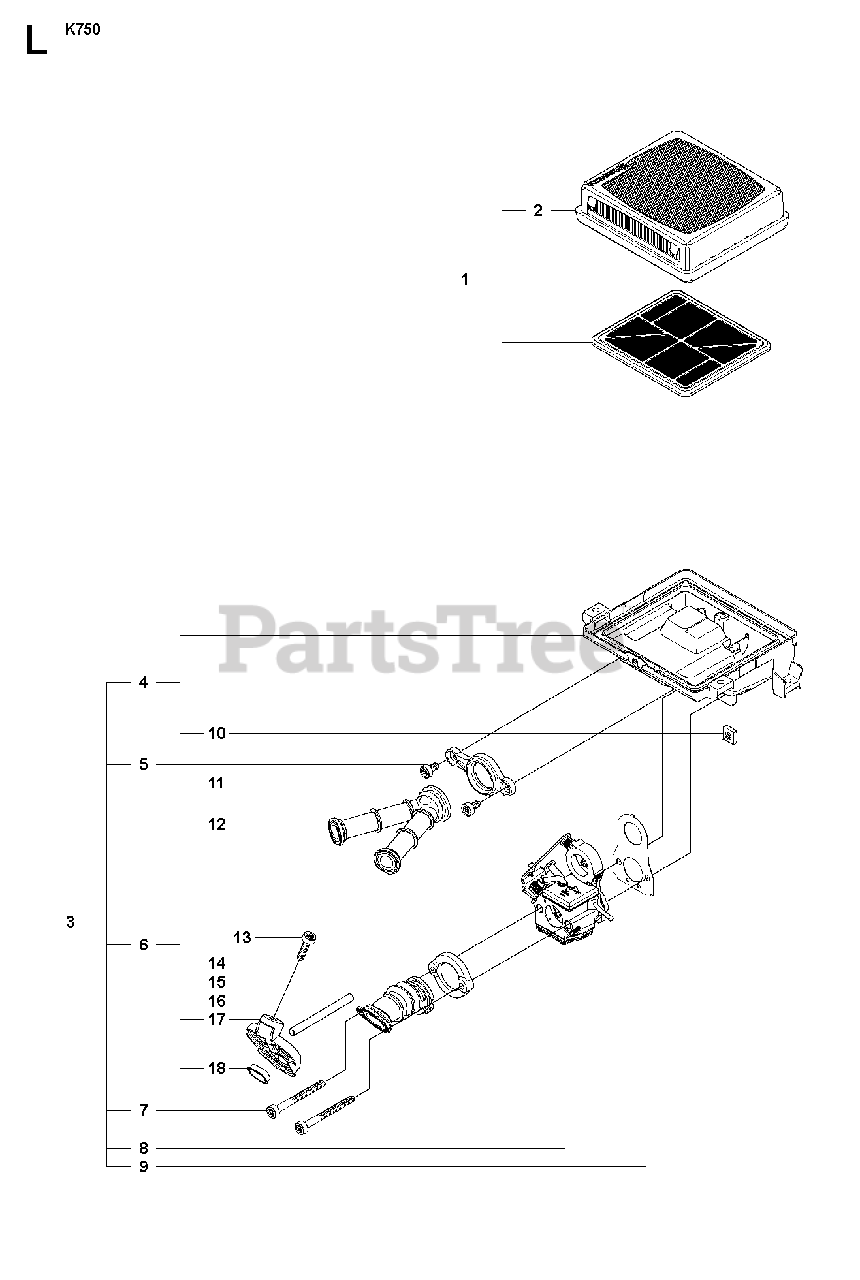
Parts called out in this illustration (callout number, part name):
1	FILTERIncl. 2
2	AIR FILTER
3	CARBURETTOR BRACKETIncl. 4 - 9
4	CARBURETTOR BRACKETIncl. 10
5	SCREW ITXSCM
6	INLET PIPEIncl. 11, 12. 14 - 18
7	SCREW ITXSCM
8	CARBURETTORZama C3-EL29
9	GASKET
11	FLANGE INLET PIPE
12	INLET PIPE
13	SCREW ITXSCM
14	FLANGE INLET PIPE
15	INLET PIPE
16	IMPULSE HOSE
17	PLATE
18	INSERT
